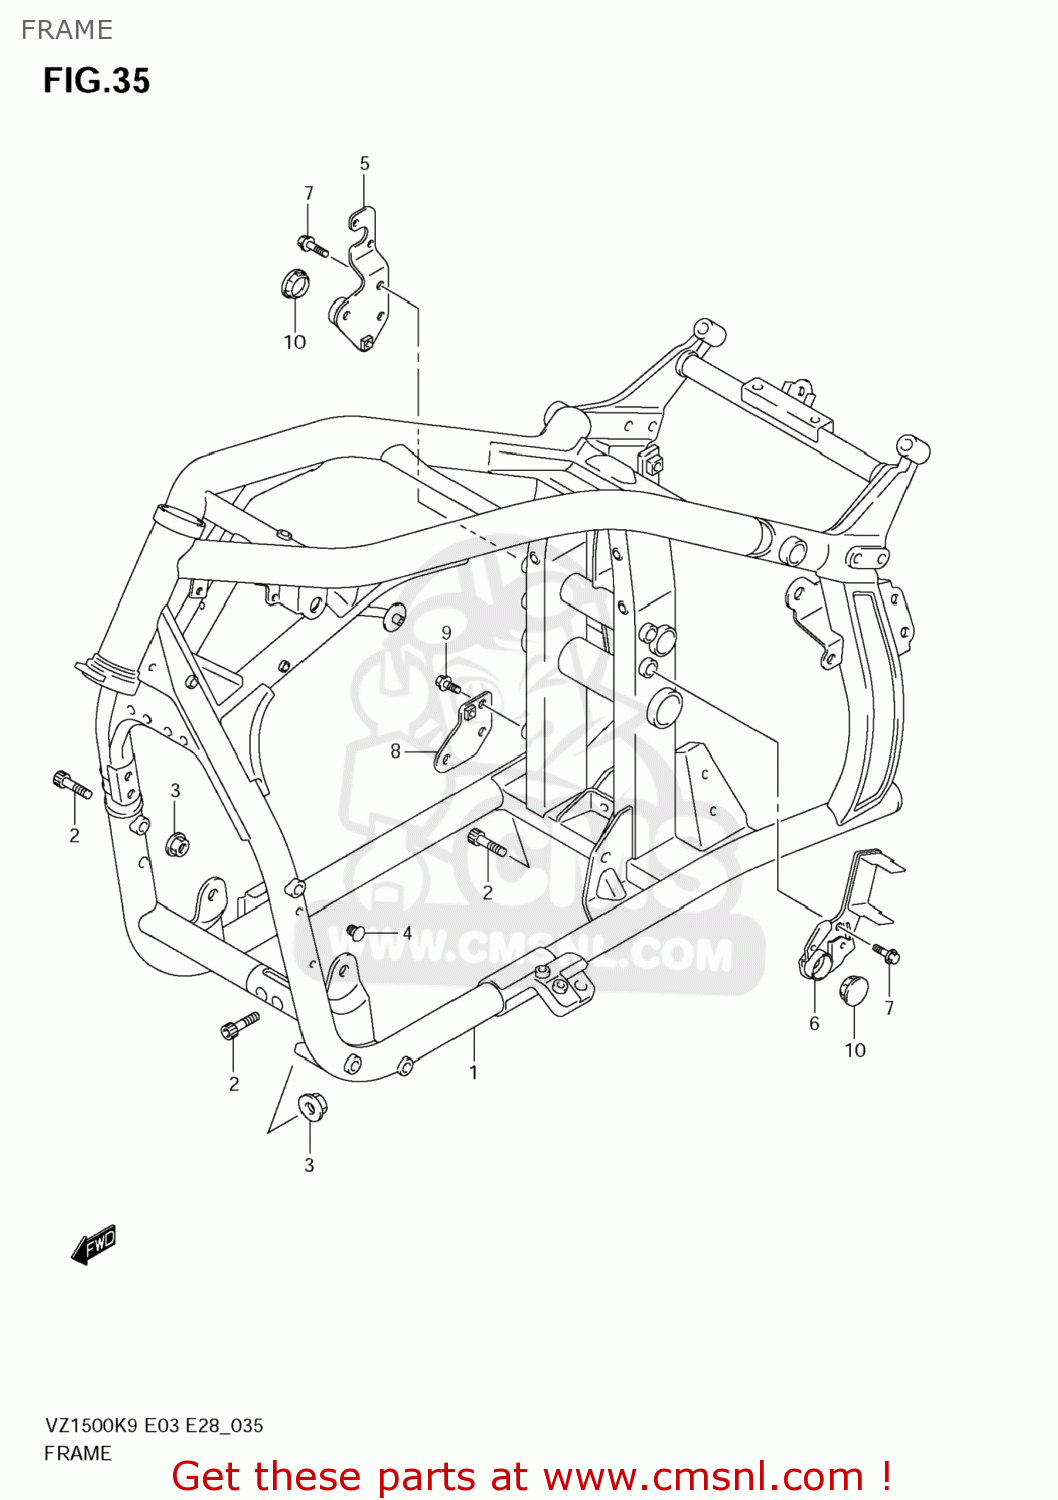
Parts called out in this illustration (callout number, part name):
1	FRAME(BLACK)
2	BOLT
3	NUT
4	CAP(OD:14)
5	PLATE,ENG MTG RR,R
6	PLATE,ENG MTG RR,L
7	BOLT
8	PLATE,ENG MTG RR LOW,R
9	BOLT
10	CAP,ENG MTG BOLT
